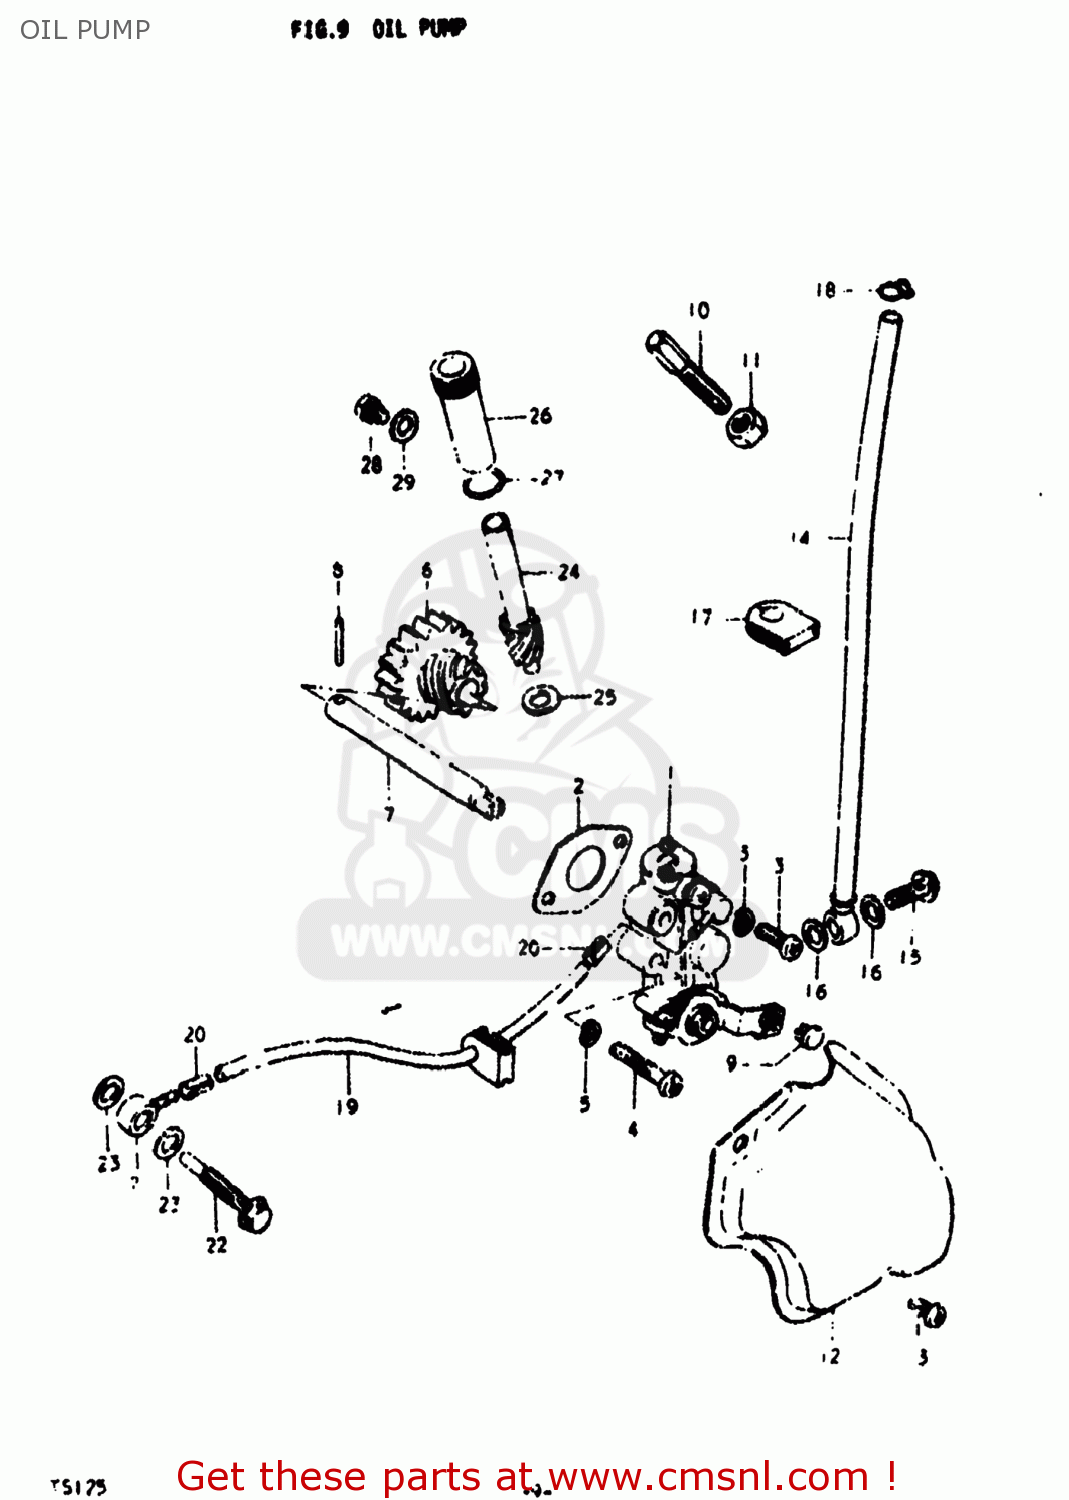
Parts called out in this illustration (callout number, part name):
1	PUMP ASSEMBLY,OIL
2	GASKET,OIL PUMP (MCA)
3	SCREW
4	SCREW
5	LOCK WASHER
6	GEAR,OIL PUMP DRIVE
7	SHAFT,OIL PUMP DRIVE
8	PIN(2.5X19.8)
9	TERMINAL,CABLE
10	BOLT
11	NUT
12	CAP,OIL PUMP INSPECTION
13	SCREW
14	HOSE,OIL NO.1
15	UNION BOLT
16	GASKET(6.2X11X1).2 (NAS)
17	GROMMET
18	CLIP
19	HOSE,OIL NO.2
20	CLIP
21	UNION
22	GASKET (NAS)
23	GASKET(6.2X11X1).2 (NAS)
24	GEAR,TACHOMETER DRIVEN(NT:10)
25	WASHER(8X13.7X1)
26	SLEEVE,TACHOMETER DRIVE GEAR
27	O RING(D:1.3,ID:9.6)
28	BOLT
29	WASHER
